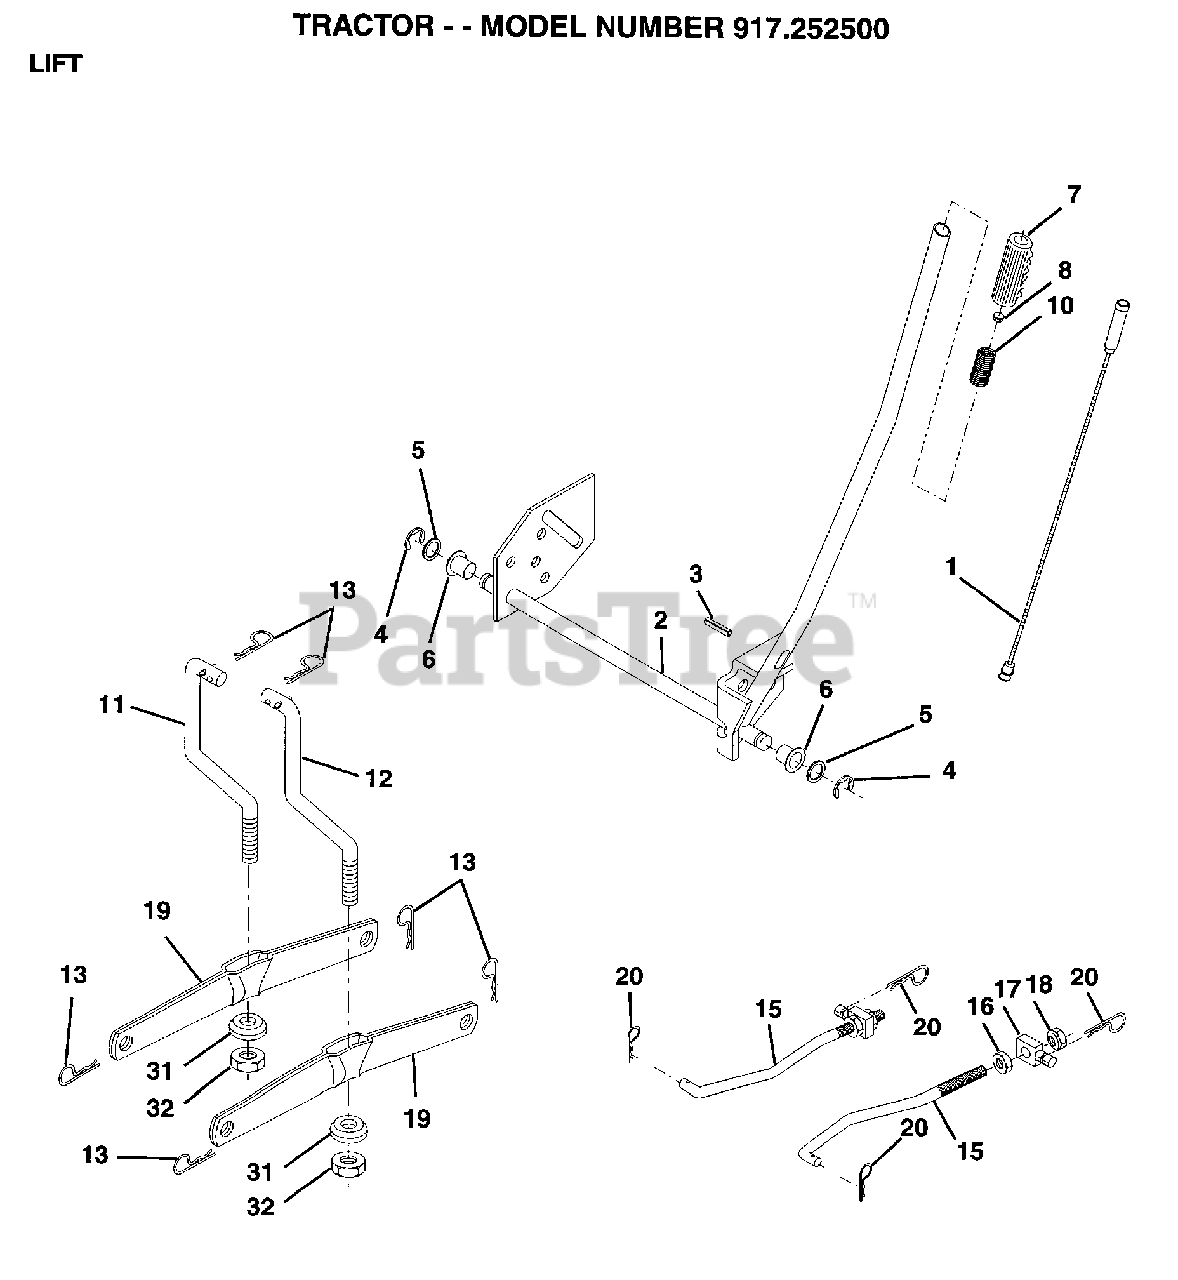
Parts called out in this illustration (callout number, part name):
1	WIRE ASM
3	PIN-GROOVE LT
5	WASHER
6	NYLON BEARING
7	GRIP HANDLE
15	LINK.FRONT
16	NUT
19	ARM SUSP REAR
20	RETAINER.SPRING
31	BEARING PVT LH
32	NUT.CROWNLOCK.3/8
